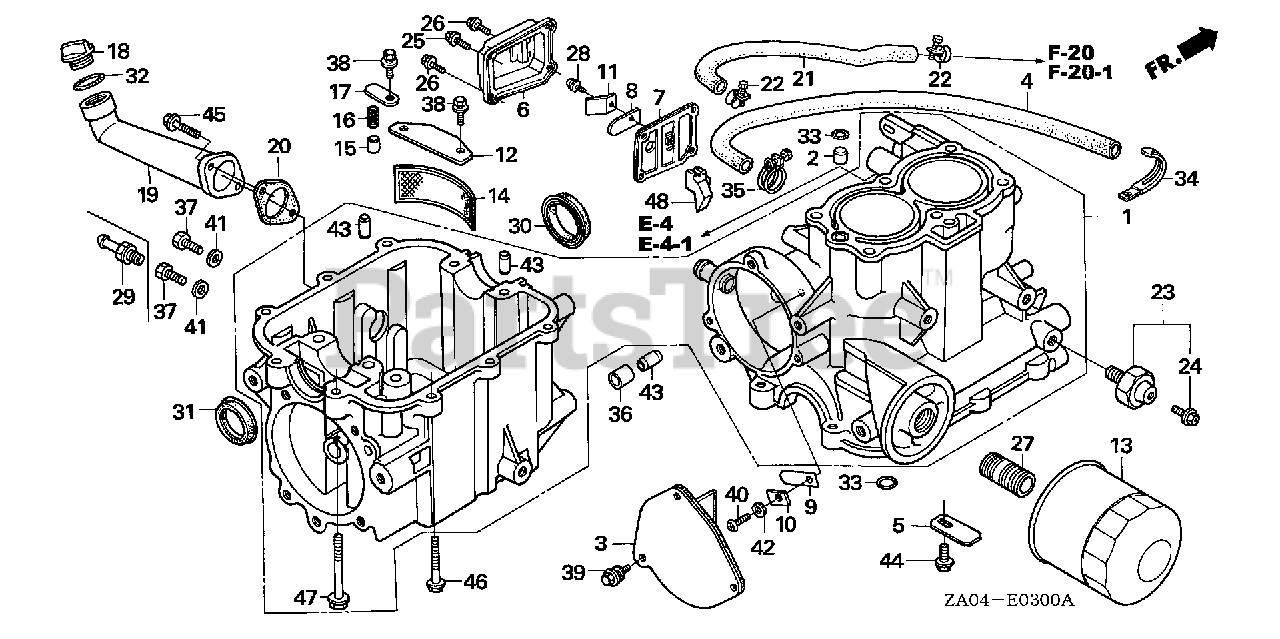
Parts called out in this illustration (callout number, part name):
1	CYLINDER ASSY.
2	ORIFICE, OIL CONTROL
3	COVER ASSY., BREATHER
4	TUBE, BREATHER (NOT AVAILABLE)
5	COVER, BREATHER RETURN
9	PLATE, VALVE
10	STOPPER, VALVE
12	PLATE, OIL FILTER
13	FILTER, OIL (TOYO ROKI)
14	SCREEN, OIL FILTER
15	VALVE, CHECK
16	SPRING, CHECK VALVE
17	PLATE, CHECK VALVE
18	CAP, OIL (YELLOW)
19	PIPE, OIL FILLER
20	GASKET, OIL PIPE
23	SWITCH, OIL PRESSURE
24	BOLT-WASHER (4X8) (DENSO)
27	HOLDER, OIL FILTER
30	OIL SEAL (33X48X7)
31	OIL SEAL (30X44X7)
32	O-RING (26X2.7)
33	O-RING (10.8X2.4) (ARAI)
35	CLIP A18, TUBE
36	SPACER, ENGINE MOUNTING
37	BOLT, DRAIN PLUG (12MM)
38	BOLT-WASHER (6X12)
39	BOLT-WASHER (6X16)
40	SCREW, PAN (5X10)
41	WASHER, DRAIN PLUG (12MM)
42	WASHER, SPRING (5MM)
43	PIN, DOWEL (10X16)
44	BOLT, FLANGE (6X12)
45	BOLT, FLANGE (6X16)
46	BOLT, FLANGE (6X28)
47	BOLT, FLANGE (8X55)
